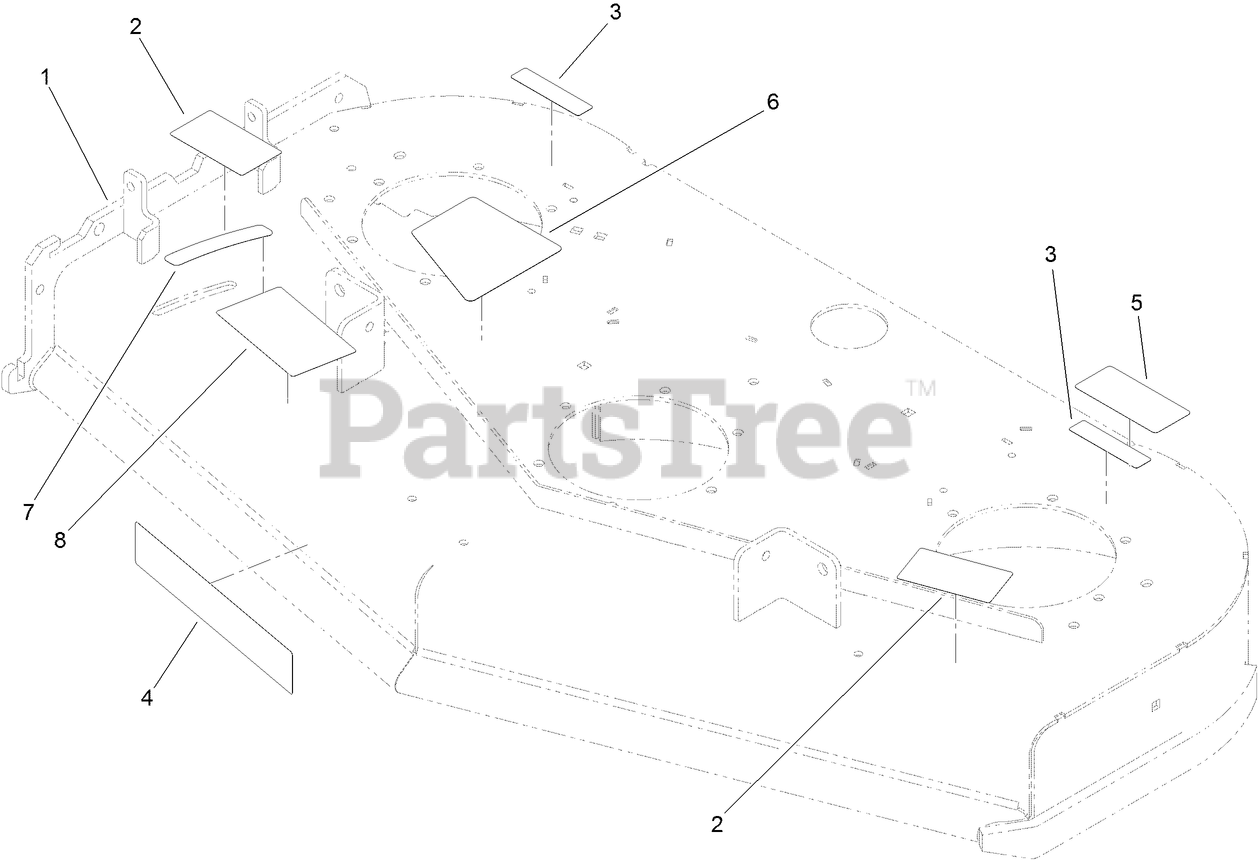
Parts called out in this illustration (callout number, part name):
1	DECK ASM
2	DECAL-DANGER
3	DECAL-DANGER
5	DECAL-TORQUE, BLADE BOLT
6	DECAL-BELT TENSION, CE
7	DECAL-SETTING, BAFFLE
8	DECAL-ADJUSTMENT, BAFFLE
